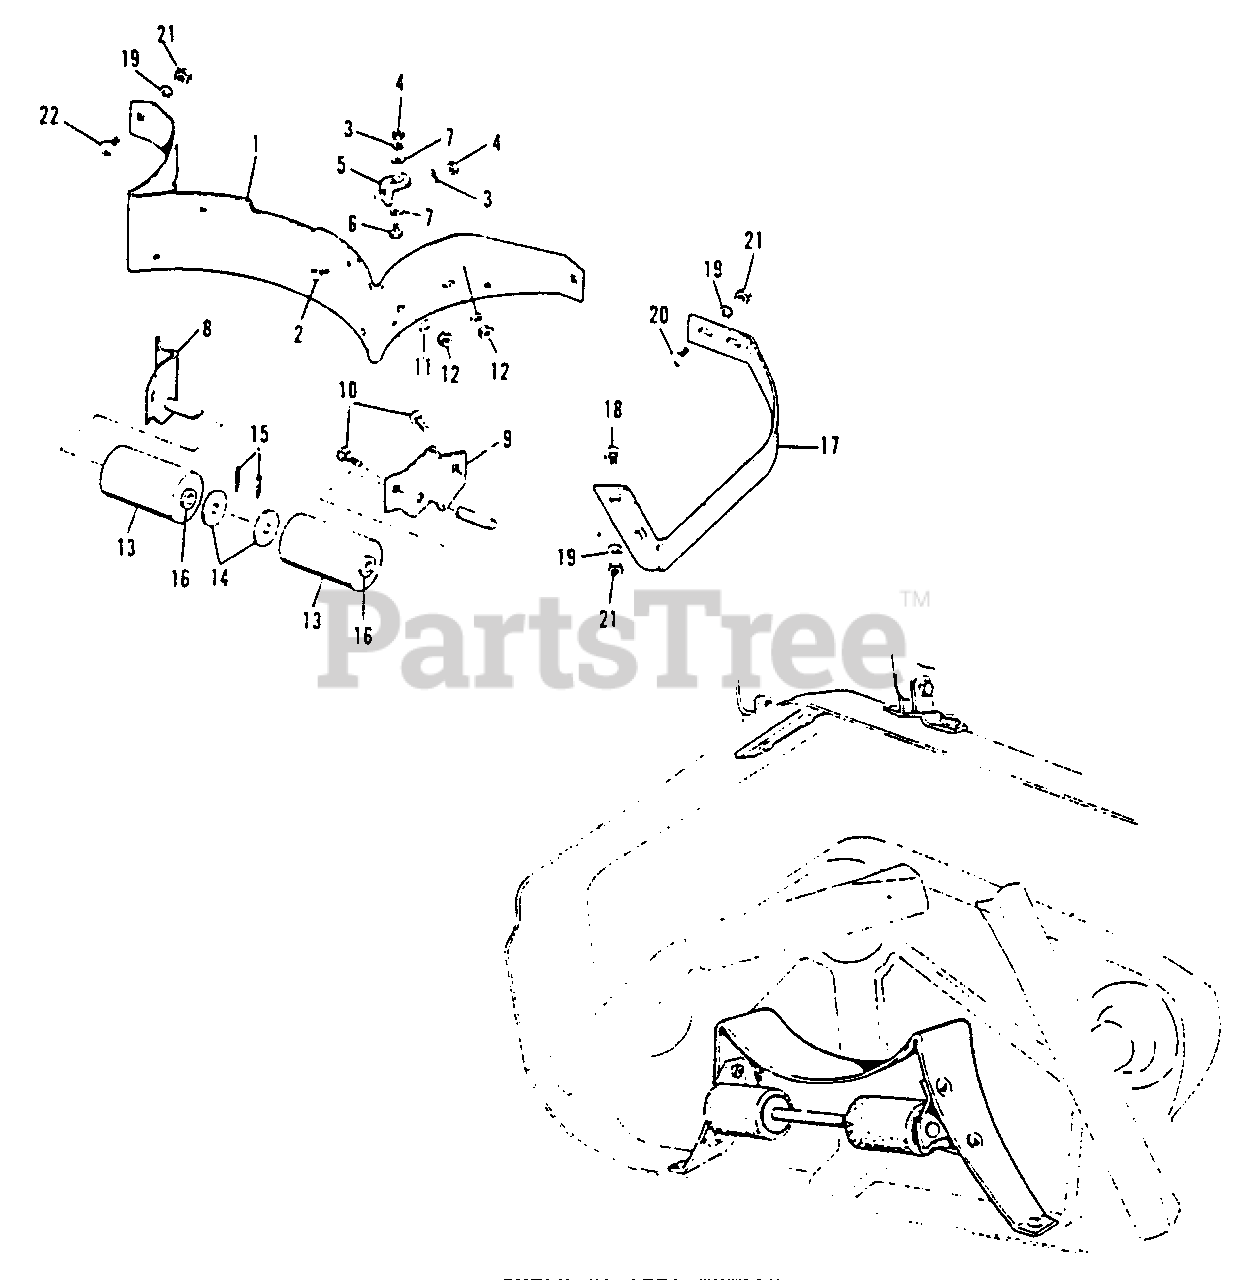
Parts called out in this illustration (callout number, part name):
2	Self Tap Hex. Screw, 1/4"-20 x 7/8"
3	Lock Washer, 1/4"
4	Full Hex. Nut, 1/4"-20
5	Baffle Clip
6	Hex. Cap Screw. 1/4"-20 x 5/8"
7	Plain Washer, 1/4"
8	Bracket & Shaft Assembly
9	L.H. Roller Bracket
10	Carriage Bolt, 5/16"-18 x 3/4"
11	Lock Washer, 5/16"
12	Full Nex. Nut, 5/16"-18
13	Roller Assembly W/Bushing
15	Cotter Pin, 3/16" x 1"
17	Housing Assembly Guard
18	Carriage Bolt, 3/8"-16 x 3/4"
19	Lock Washer 3/8"
20	Carriage Bolt, 3/8"-16 x 1"
21	Full Hex. Nut, 3/8"-16
22	Carriage Bolt, 3/8"-16 x 3/4" lg.
